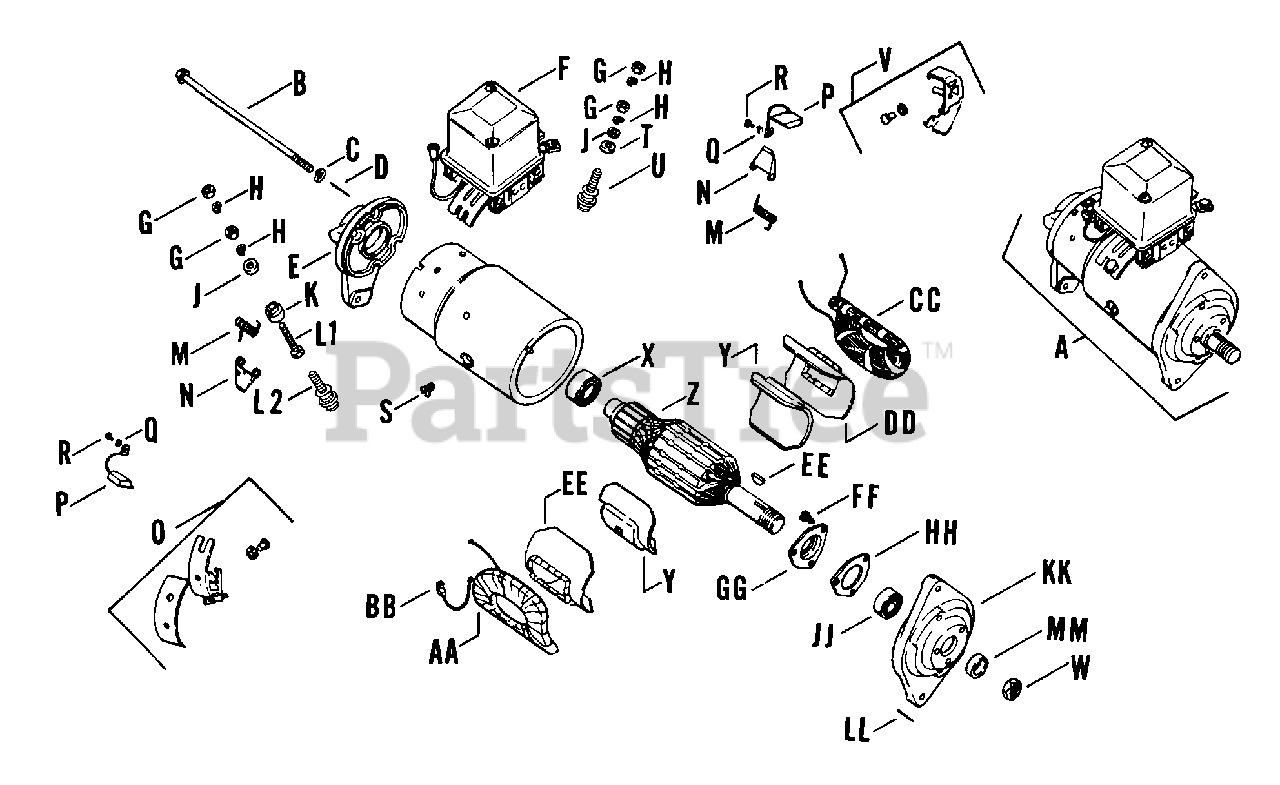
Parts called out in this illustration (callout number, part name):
C	Washer, split-thru bolt
D	PIN - DISCONTINUED
E	FRAME - DISCONTINUED
F	REGULATOR - DISCONTINUED
G	NUT - DISCONTINUED
H	WASHER - USE 272320
J	Washer, flat terminal
K	BUSHING - DISCONTINUED
M	SPRING - DISCONTINUED
N	HOLDER - DISCONTINUED
O	HOLDER - DISCONTINUED
P	BRUSH - DISCONTINUED
Q	WASHER, SPRING LOCK #6
R	SCREW, SLT PAN HD 6-32X5/16" USE 25 086 57-S
S	SCREW - DISCONTINUED
T	WASHER - DISCONTINUED
U	STUD - USE 232862
V	HOLDER - DISCONTINUED
W	NUT - DISCONTINUED
Y	SHOE - DISCONTINUED
Z	ARMATURE - DISCONTINUED
AA	COIL - DISCONTINUED
BB	CLIP - DISCONTINUED
DD	INSULATOR - DISCONTINUED
EE	KEY - DISCONTINUED
FF	SCREW - DISCONTINUED
HH	GASKET - DISCONTINUED
JJ	BEARING - DISCONTINUED
KK	FRAME - DISCONTINUED
LL	PIN - DISCONTINUED
